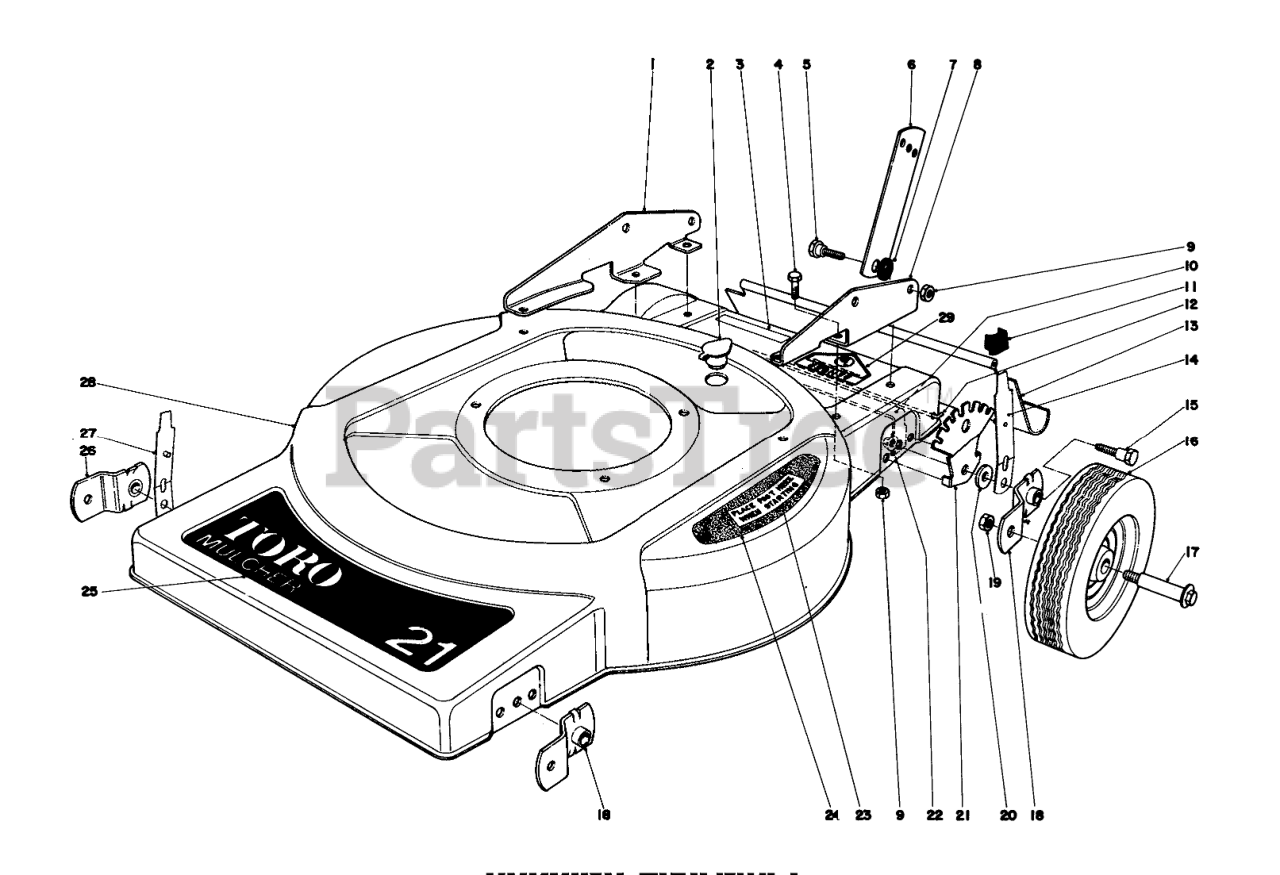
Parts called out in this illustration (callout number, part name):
1	Bracket Handle R.H.
2	WASHOUT PLUG
3	Decal-Instruction
4	SCREW-HH
5	SCREW-SHOULDER
6	Handle Latch
7	SPACER
8	Bracket Handle L.H.
9	NUT-LOCK, CONE
10	DECK SUPPORT
11	KNOB-ARM
12	SHIELD ROD
13	SHIELD - TRAILING
14	SPRING ARM ASM
15	PIVOT SCREW
16	Wheel Assembly
18	PIVOT ARM ASM A
19	Nut
20	PIVOT WASHER
21	Quadrant
23	Decal Step Pad
24	PAD STEP
25	Decal-Front Deck
26	PIVOT ARM ASM B
27	SPRING ARM ASM
28	Housing
29	DECAL-DANGER
